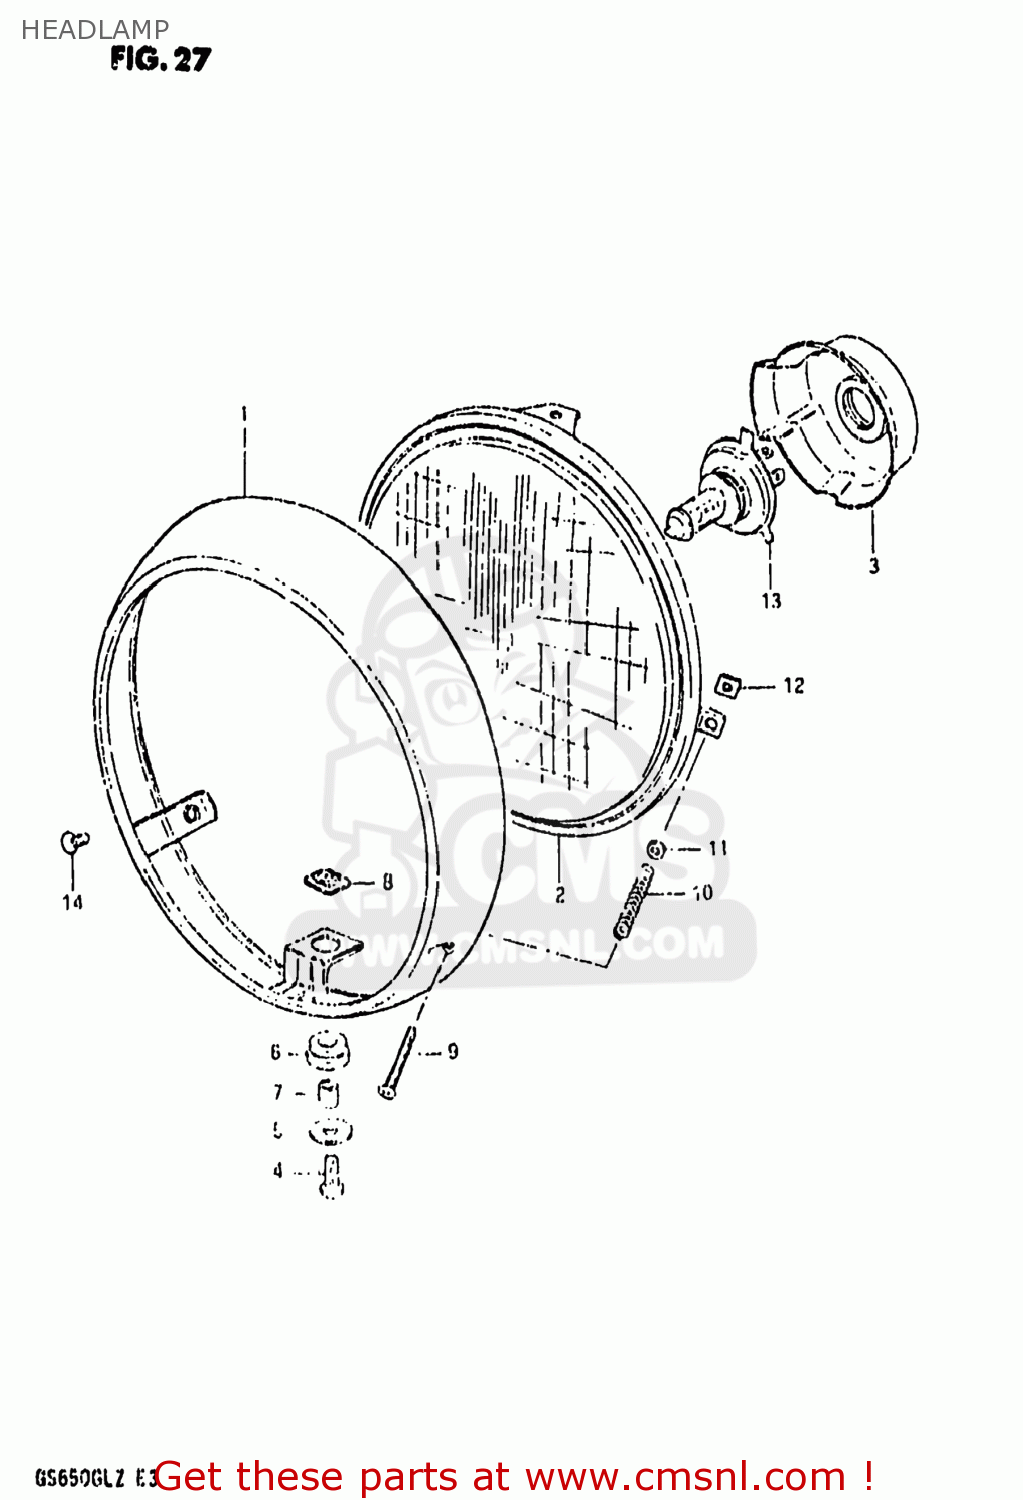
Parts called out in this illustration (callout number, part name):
1	RIM
2	LAMP UNIT
3	COVER,SOCKET
4	SCREW
5	WASHER
6	CUSHION
7	SPACER
8	NUT
9	SCREW
10	SPRING,HEADLAMP ADJUST
11	WASHER
12	NUT,HEADLAMP ADJUSTER
13	BULB(12V60/55W,H4)
14	SCREW(5X12)
